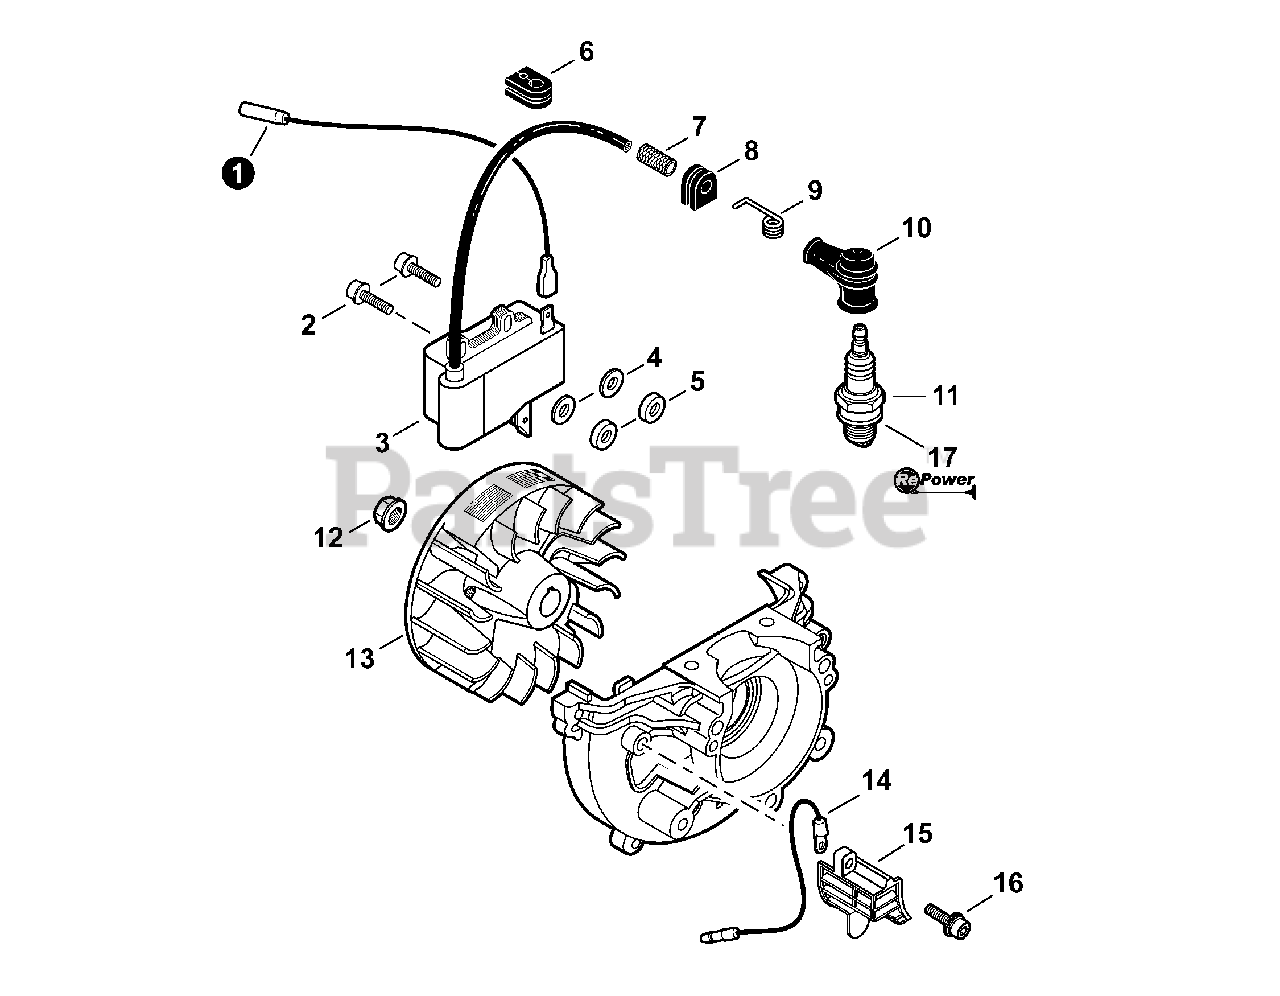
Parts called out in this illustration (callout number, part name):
1	LEAD - IGNITION
3	COIL, IGNITION
4	WASHER 4mm
5	INSULATOR 4
6	GROMMET
7	TUBE, INSULATOR
8	GROMMET, HT CORD
9	TERMINAL, SPARK PLUG
10	CAP, SPARK PLUG
11	SPARK PLUG - BPM-8Y
12	NUT, FLANGE M8
13	FLYWHEEL
14	LEAD - GROUND
15	COVER, DUST
16	BOLT 5×16
17	TUNE-UP KIT - REPOWER
